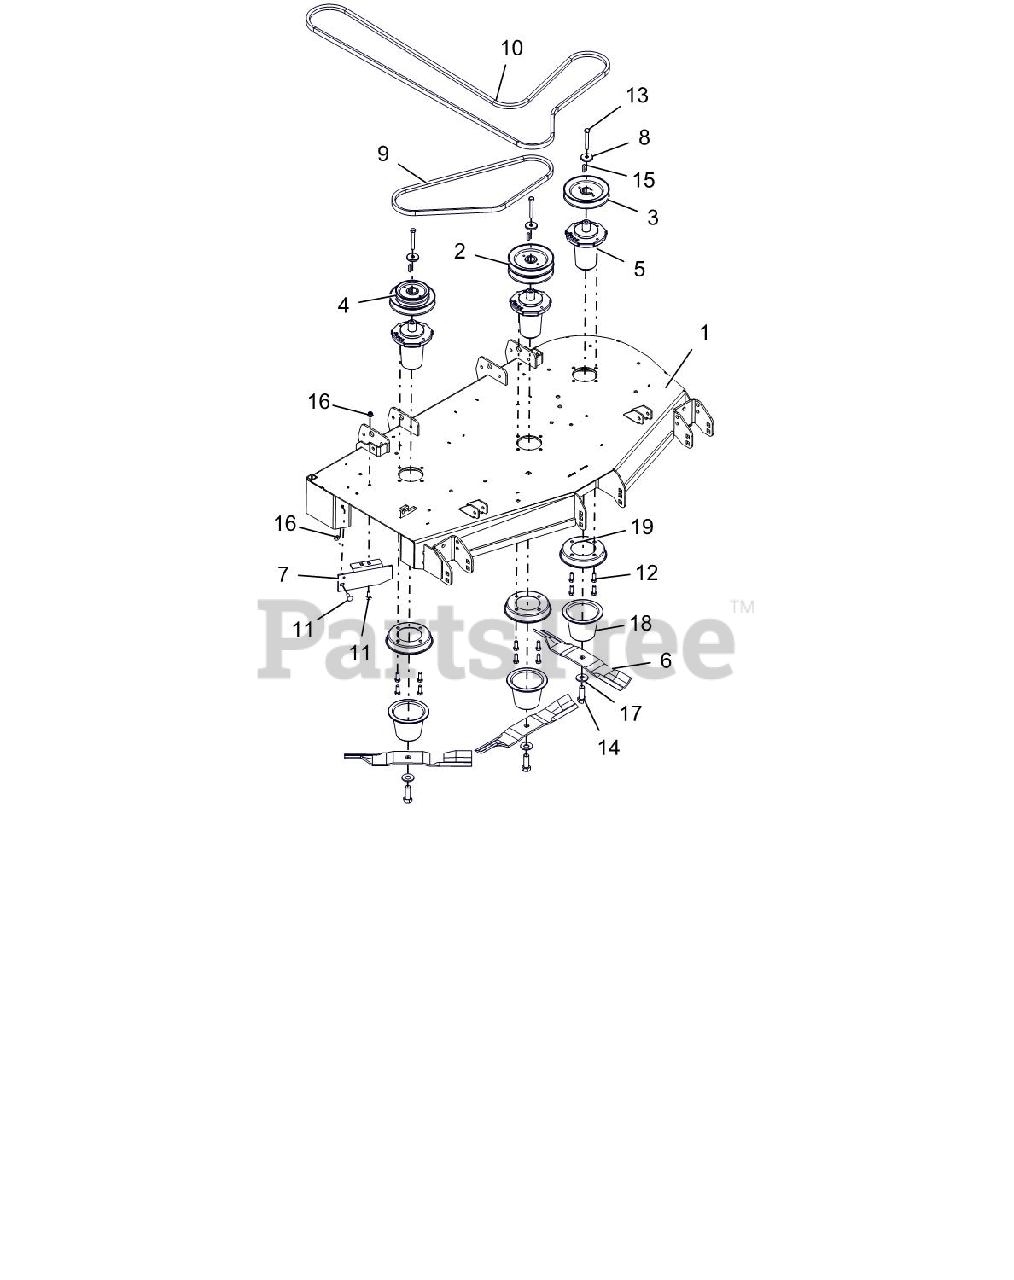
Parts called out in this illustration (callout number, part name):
1	DECK, PT48 W/SAFETY DECALS
2	PULLEY, DOUBLE-1"ID X 5.75"OD
3	PULLEY, V-1" ID X 5.75" OD
4	PULLEY, DBL-1"IDX5.75"&4.25"OD
5	ASM, MAINT FREE SPINDLE
6	BLADE, 16.19" MOWER (HI-LIFT)
7	44"-48" SIDE DISCH BAFFLE -RED
8	RETAINER, SHEAVE
9	V-BELT, B-COGGED
10	V-BELT, B RAW EDGE EPDM
11	@BLT-RDHDSQNK .31-18X1.00 G5YZ
12	BLT-HEX .38-16X1.0 GR8 YZ EP30
13	BLT-HEX .38-16X2.75 GR8 YWZC
14	BLT-HEX .62-18X1.75 GR8 YWZC
15	KEY, SQ .25X.25X1.00 RC 40-50
16	@NUT-LK-NYL-FLG .31-18 YWZC
17	WSHR-BLVL .669X1.535X.138
18	GUARD, SPINDLE LOWER
19	GUARD, SPINDLE TOP
